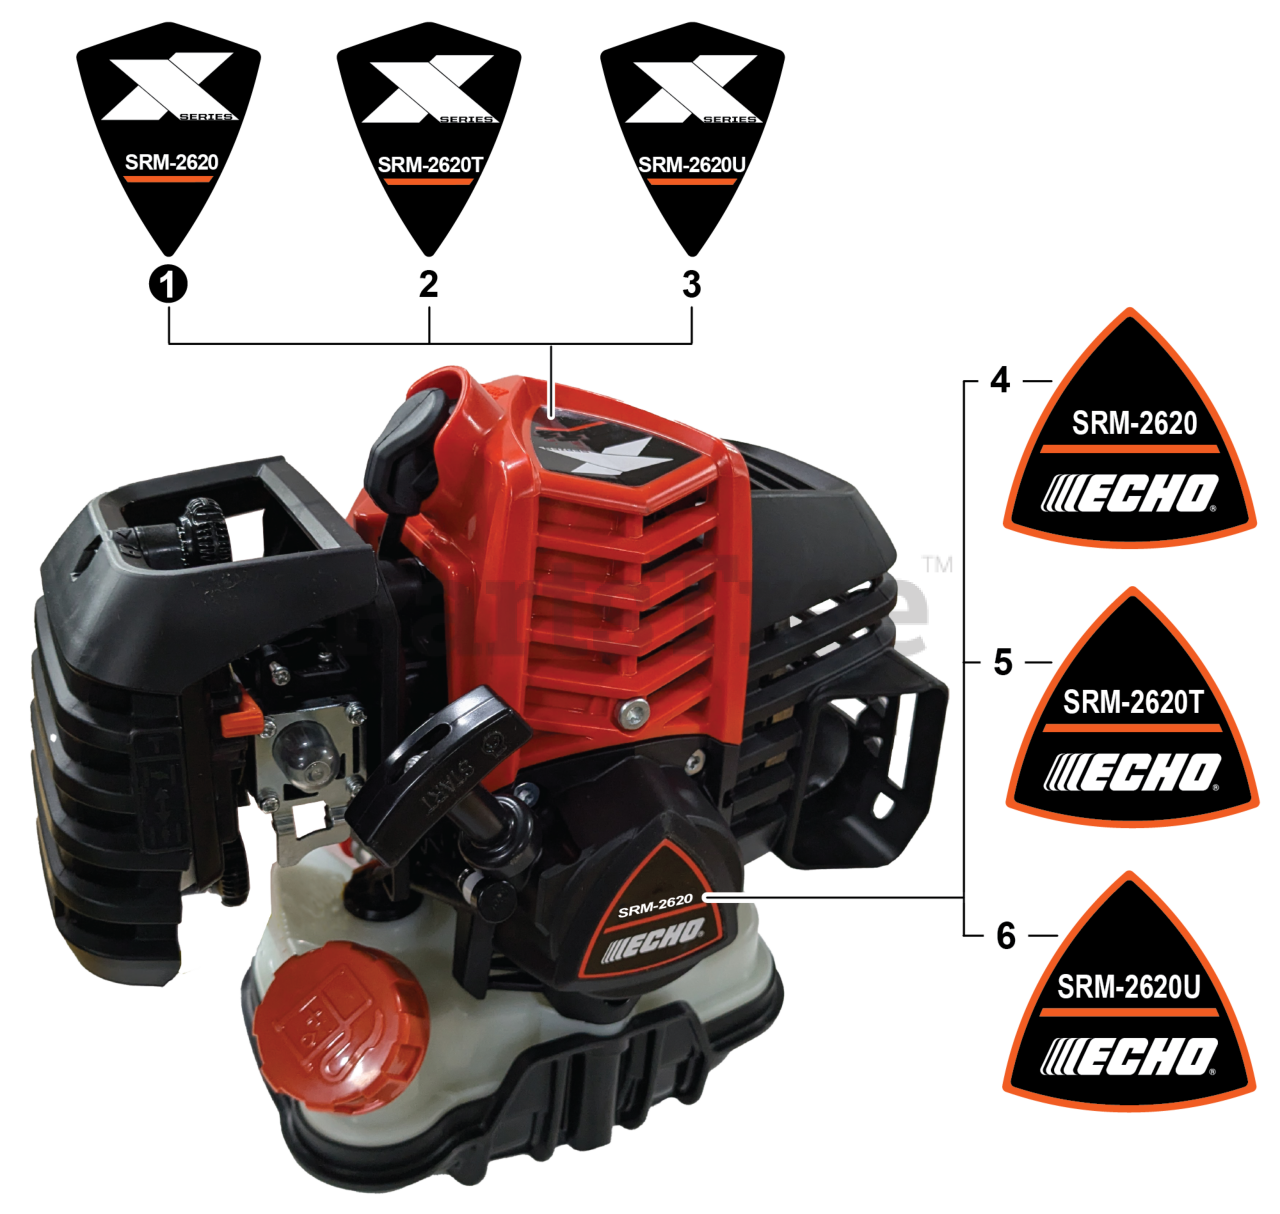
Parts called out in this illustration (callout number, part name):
1	LABEL - MODEL SRM-2620
2	LABEL - MODEL SRM-2620T
3	LABEL - MODEL SRM-2620U
4	LABEL - STARTER - SRM-2620
5	LABEL - STARTER - SRM-2620T
6	LABEL - STARTER - SRM-2620U
